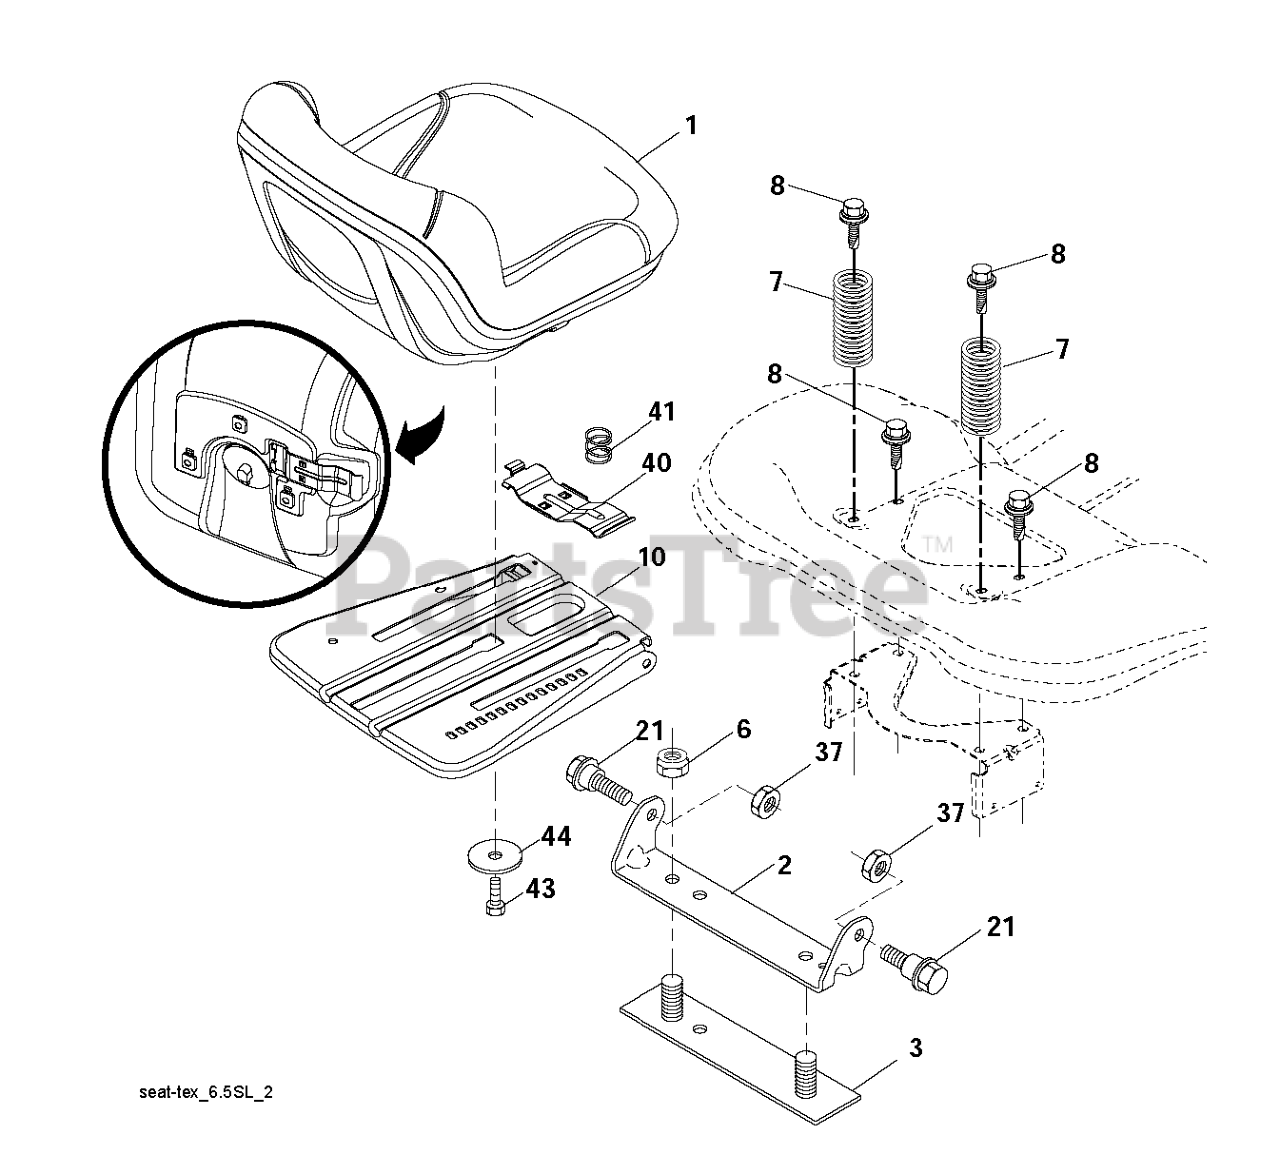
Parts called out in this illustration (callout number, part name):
1	RP SEAT, TH150, GREY, MILSCO
2	BRKT.PIVOT.FENDER
3	STRAP
6	NUT
7	SPRING COMPRESSION
8	BOLT.5/16-18UNCX3/4 W/SEMS.BLK
10	PAN.ASM.SEAT.3PT
21	BOLT.SHOULDER.5/16-18
37	NUT.71038.31-18.HEX.NYLOCK
40	HANDLE.SLIDE.SEAT.TEX.BLACK
41	SPRING.LATCH.SEAT.TEX
44	WASHER 13/32 X 2-3/8 X 12GA
